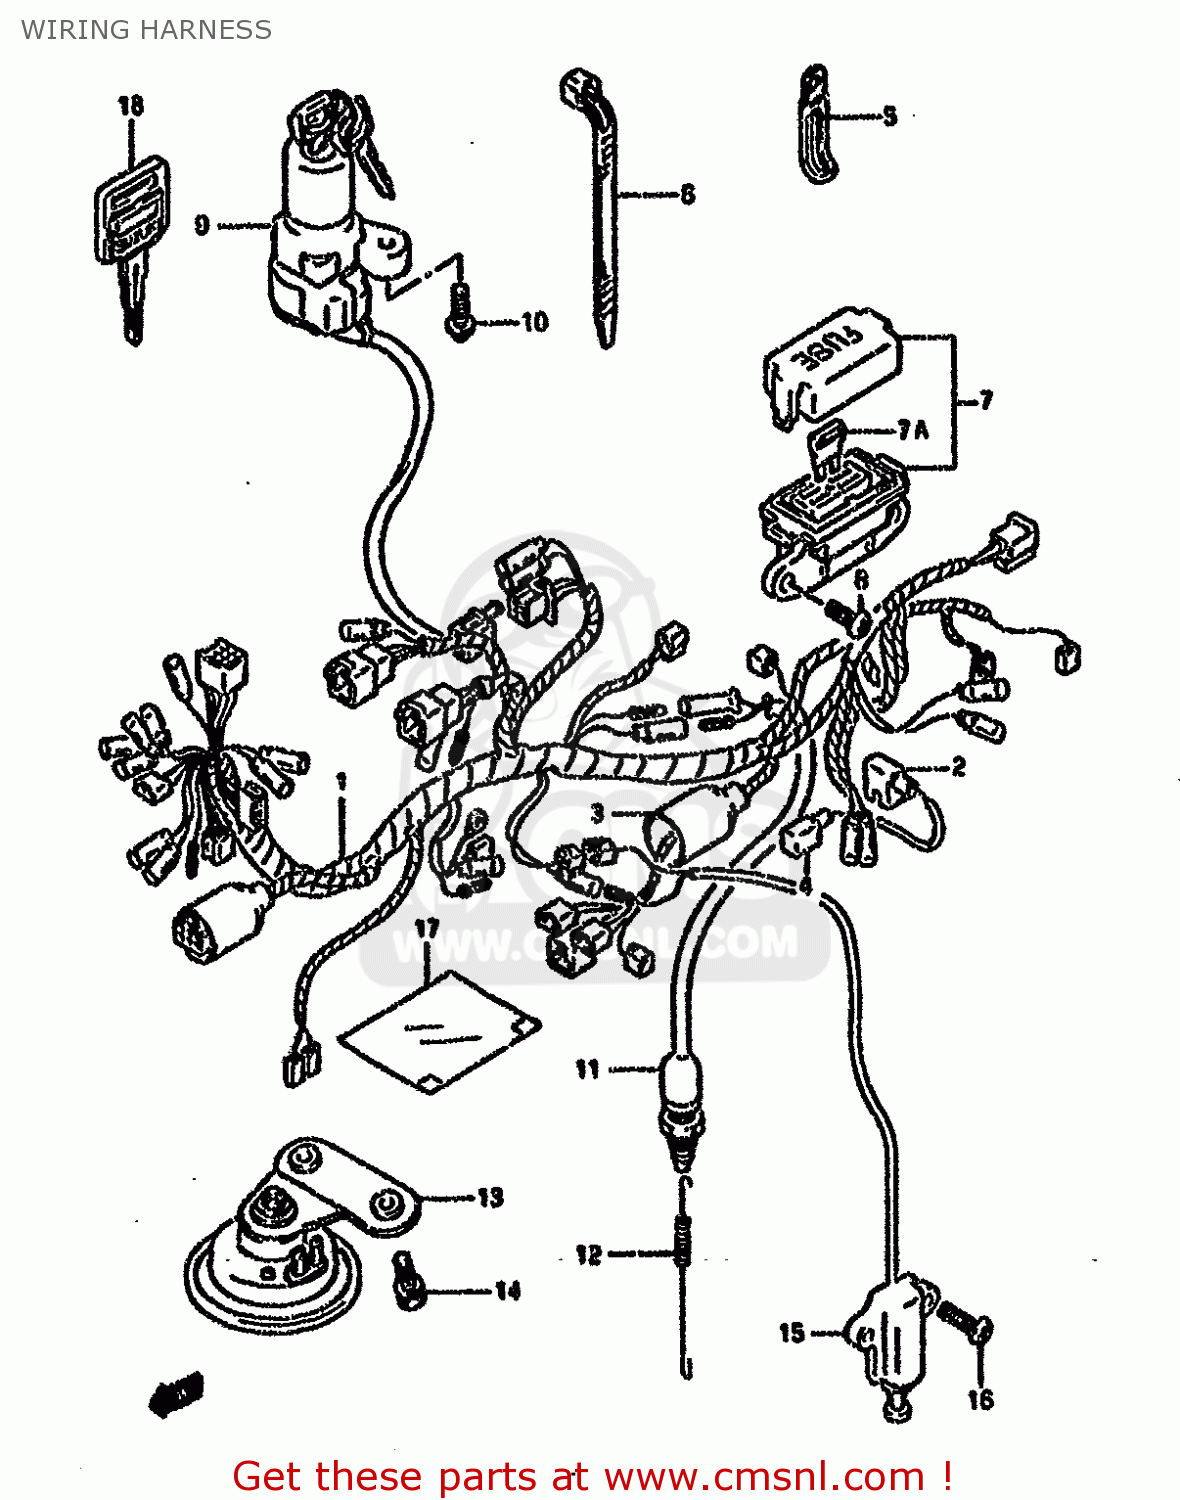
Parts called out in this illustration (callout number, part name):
1	HARNESS,WIRING
2	COVER,DECOMPRESSION CONTROL UNIT
3	BOOT,WIRING HARNESS
4	CAP,BATTERY PLUS
5	CLAMP(L:65)
6	CLAMP(L:95)
7	BOX ASSY,FUSE
7A	FUSE(10A)
8	SCREW 6X12
9	LOCK ASSEMBLY,STEERING
10	SCREW(6X18)
11	SWITCH ASSY,STOP LAMP
12	SPRING
13	HORN ASSY
14	BOLT
15	SWITCH ASSEMBLY,SIDE STAND
16	SCREW
17	COVER,WIRING HARNESS
18	KEY,BLANK
